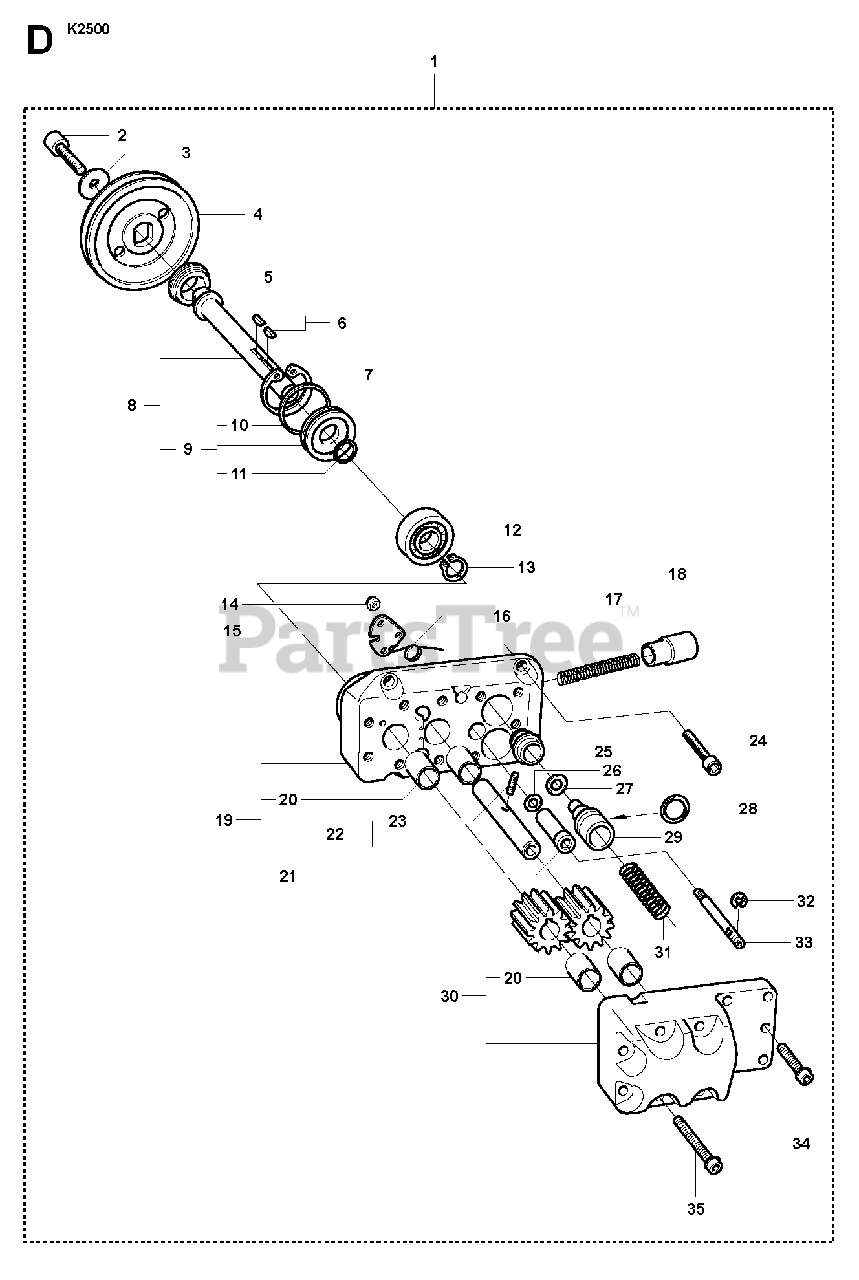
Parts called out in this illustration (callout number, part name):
1	HYDRAULIC MOTORIncl. 2 - 36
6	WOODRUFF KEY
14	HEXAGON LOCKING NUT
24	SCREW IHSCM
34	SCREW IHSCFM
35	SCREW IHSCFM
